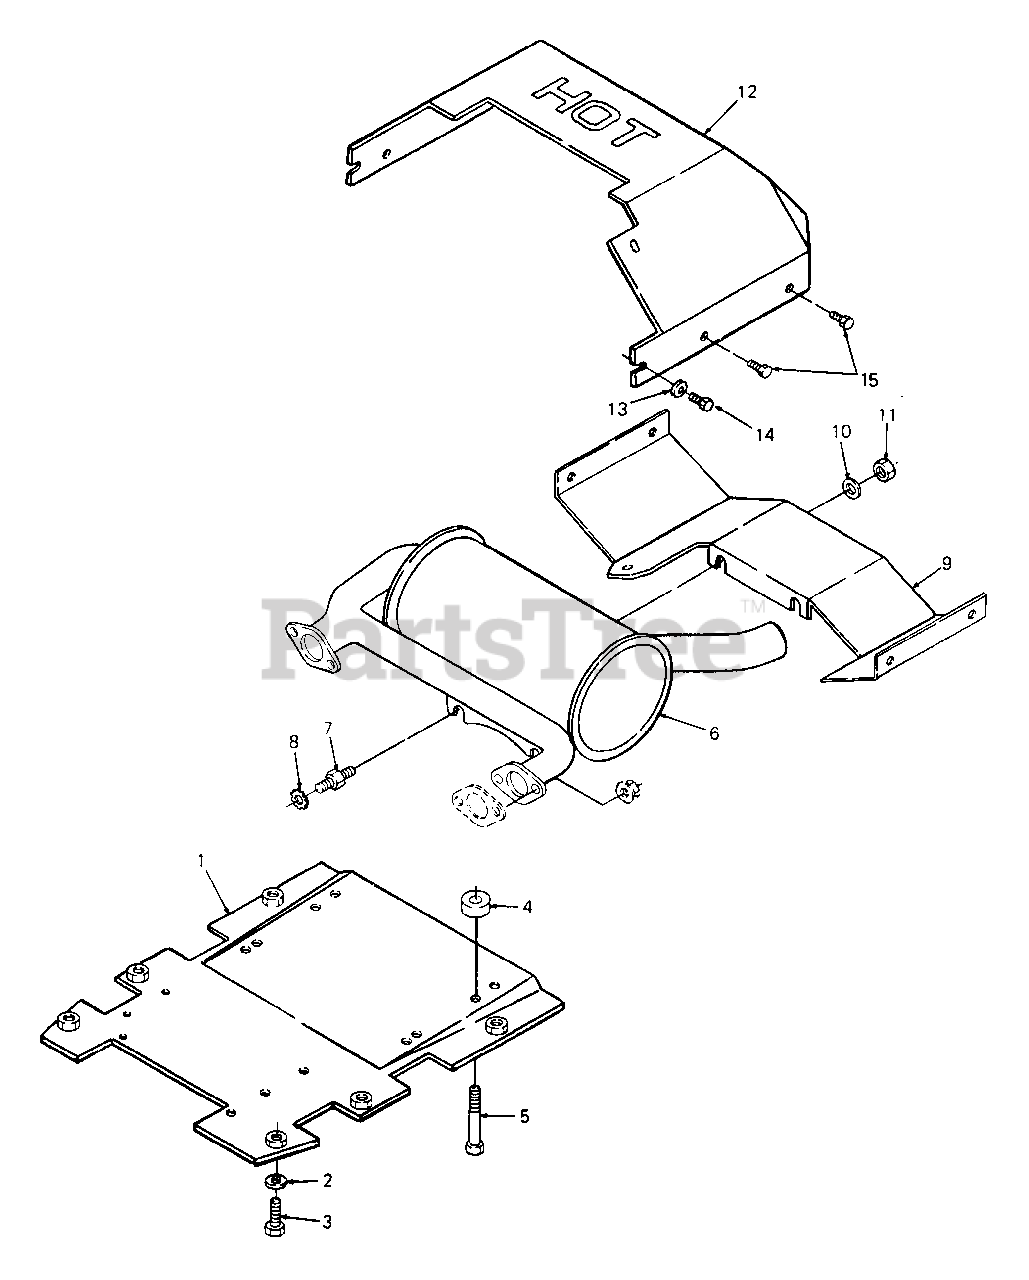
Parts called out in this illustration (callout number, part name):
3	Bolt, Patch, 3/8-16 x 1.0 Lg
4	Spacer, .423 x 1.0 x .469 Lg
5	Bolt, Patch, 3/8-16 x 2.25 Lg
7	Stud, 7/16-14 UNC-2A Thd
8	Washer, External Lock, .45 x .75 x .03 Thk
11	Nut, Hex, 7/16-14 GR5
12	Duct, Engine
13	Washer, Flat, .281 x .50 x .063 Thk
14	Bolt, Hex, M6-1.0 x 10 MM Lg GR5
15	Screw, Hex Wash Hd Tapp, #10 x .50 Lg
